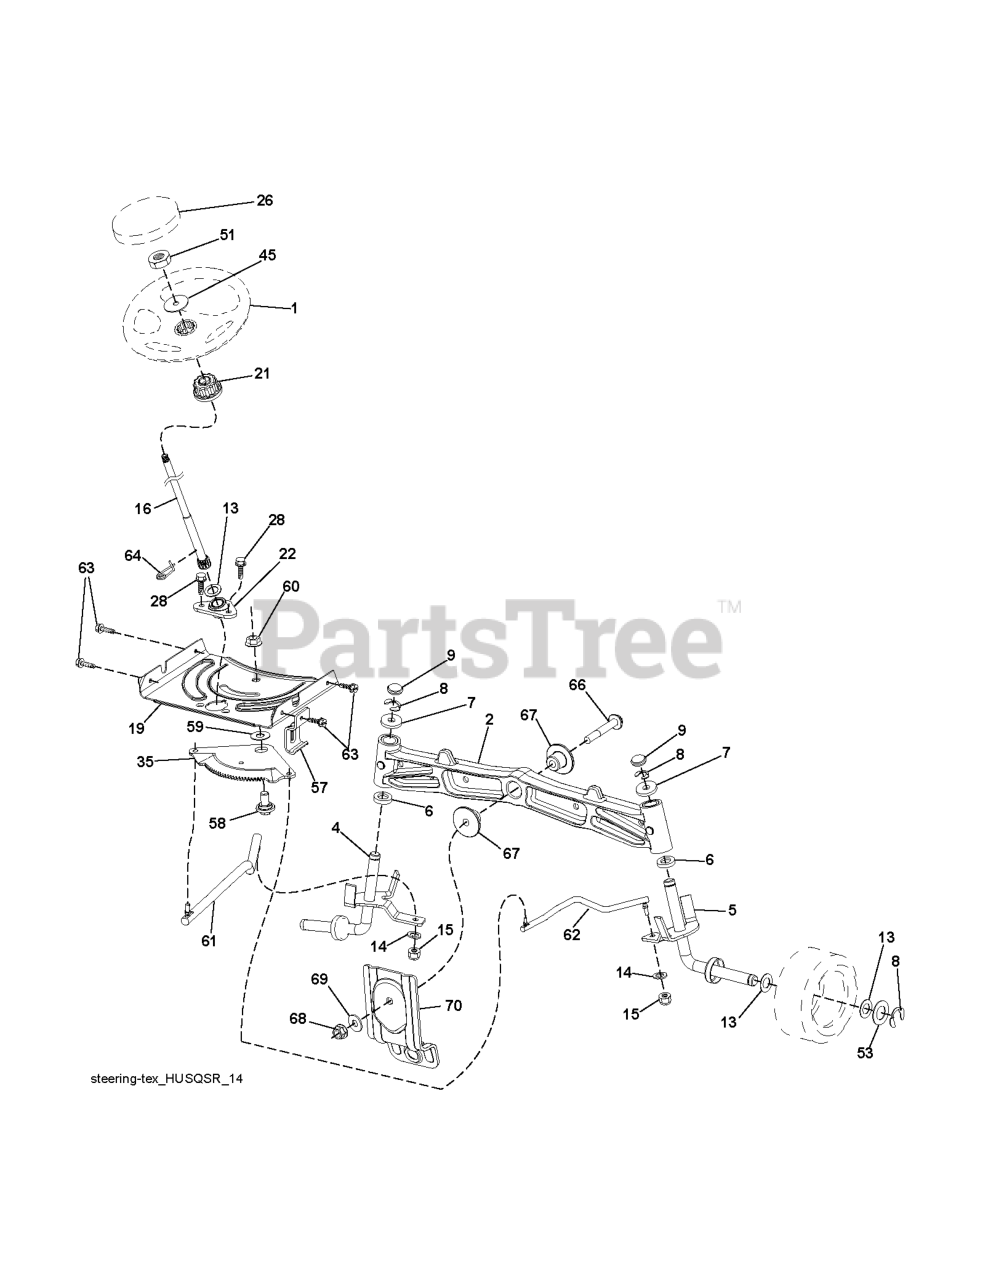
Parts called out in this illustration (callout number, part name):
1	RP WHEEL.STEER.HUSQ.PREM.OVMLD
2	AXLE.CAST.IRON
4	SPINDLE.WELDED.LH.16"TEX
5	SPINDLE.WELDED.RH.16"TEX
6	THRUST WASHER
9	CAP.SPINDLE.BLACK
14	WASHER, LOCK 3/8
15	NUT CROWNLOCK 3/8-24
16	SHAFT.STEER.STEALTH.DD
19	PLATE.STEER.DDL.NLT/NG
21	ADAPTER, WHEEL STNG..
22	BUSHING.ASM.STEERING.A
26	RP INSERT.CAP.WHL.STRG.HUSQ.
28	SCREW, 3/8-16X3/4
35	GEAR.SECTOR.PLATE.DDL.
45	WASHER 9/16"ID, 2 3/8"OD
51	NUT.HEX.1/2-20
53	WASHER.HARDENED
57	BRKT.UPSTOP.GT/LT.TEX
58	BOLT.SHOULDER.SECTOR.P
59	WASHER.THURST.SECTOR.S
60	NUT FLANGE LOCK 5/8-11
61	DRAGLINK.LH.BALLSTUD.D
62	DRAGLINK.RH.BALLSTUD.D
63	SCREW
64	RETAINER.CLIP.SPRING.S
66	BOLT HEX FGHD 7/16-14 X 3 SERR
67	BUSHING.PM.FRONT AXLE
68	NUT.LOCK.FLANGE.7/16
69	WASHER.1.5X.505X.118
70	BRKT.DECK.SUSPENSION.F
